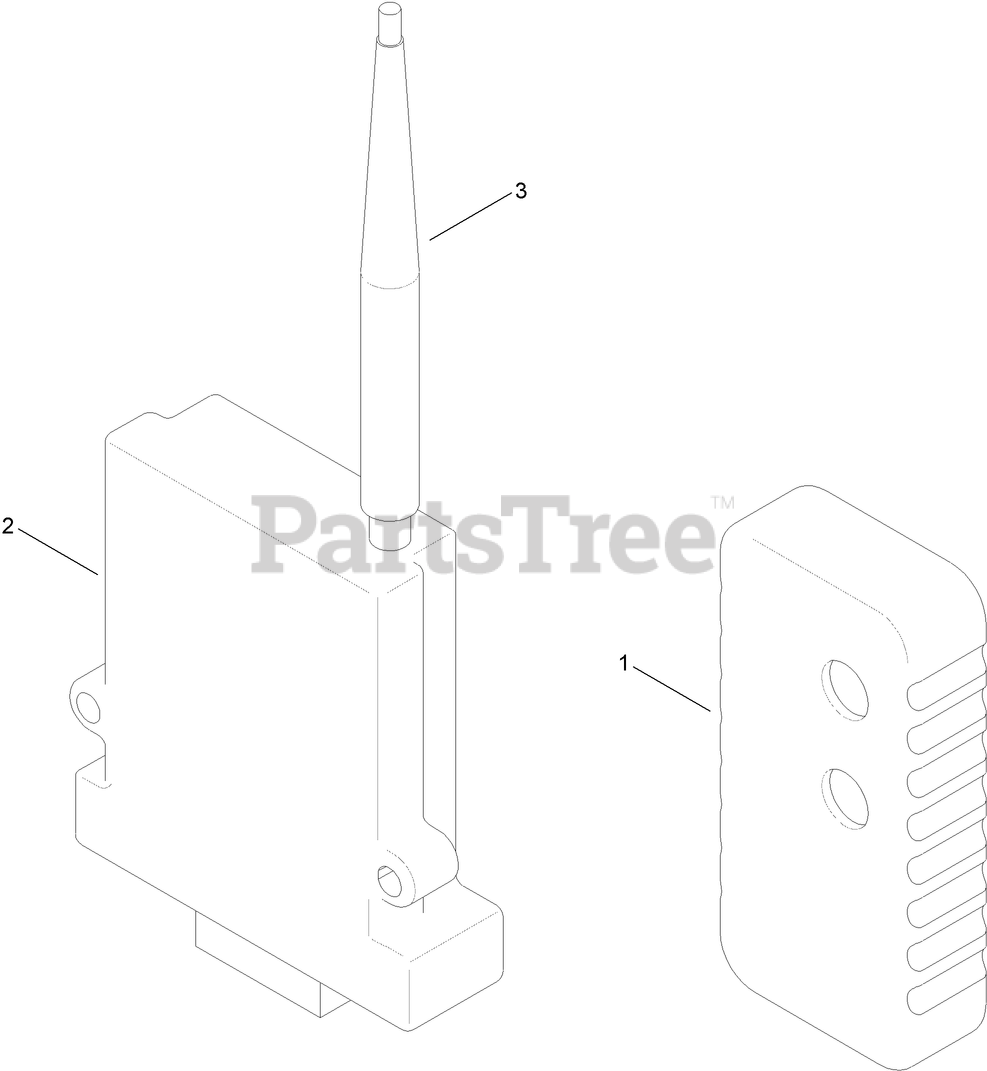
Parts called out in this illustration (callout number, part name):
1	HANDHELD-LOCKOUT
2	BASE UNIT-LOCKOUT
3	ANTENNA-LOCKOUT
